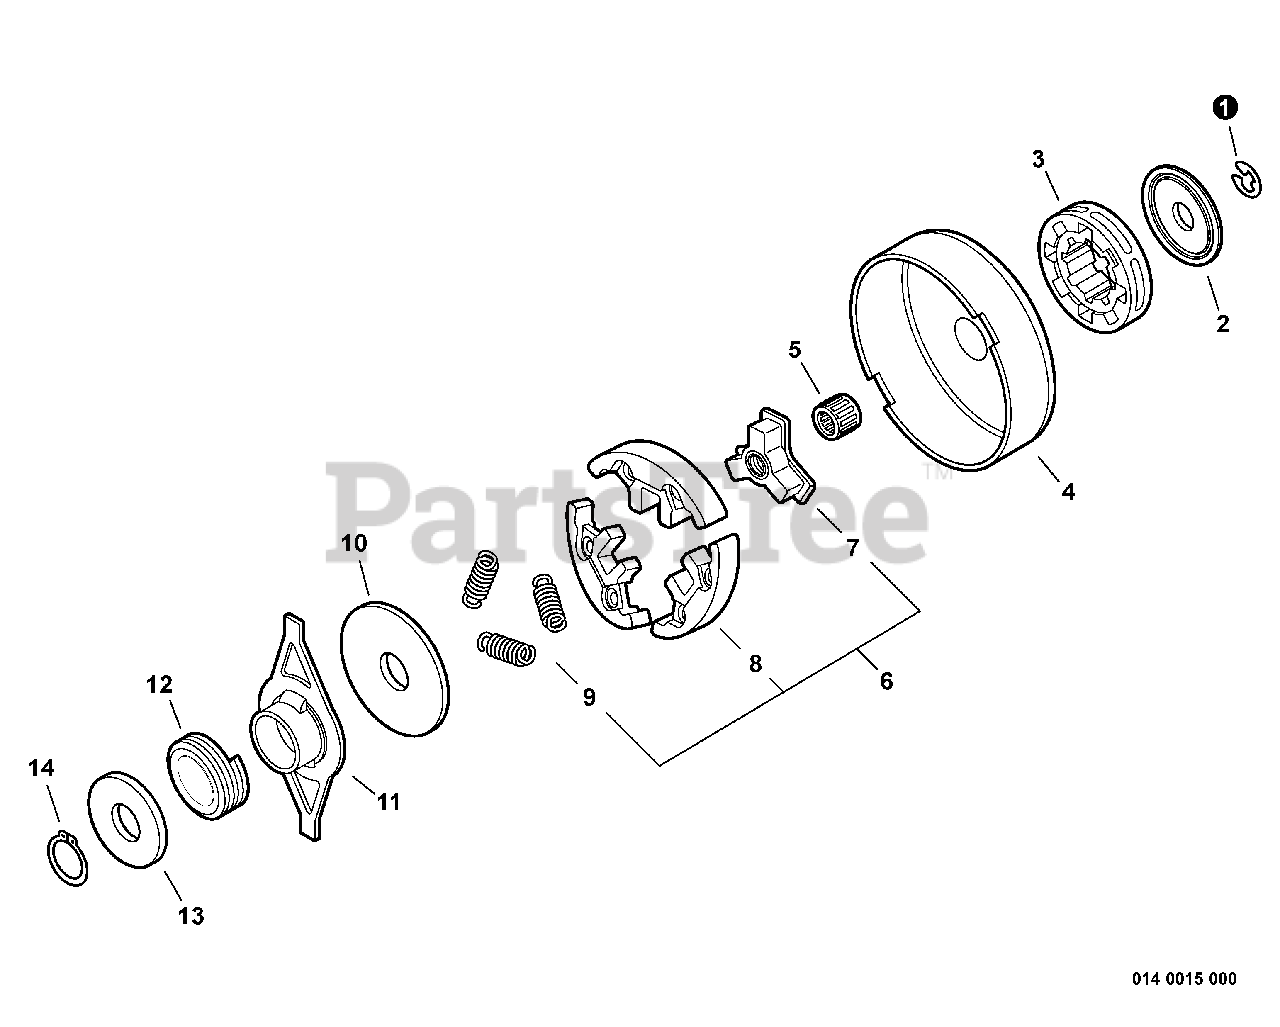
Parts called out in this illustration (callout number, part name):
1	RING, RETAINING - 8
2	WASHER - 10
3	SPROCKET, RIM
4	DRUM, CLUTCH
5	BEARING, NEEDLE
6	CLUTCH ASSY
7	HUB, CLUTCH
8	CLUTCH SHOE SET
9	SPRING, CLUTCH
10	PLATE, CLUTCH
11	RETAINER
12	GEAR - WORM
13	WASHER - 15
14	RING, RETAINING - 15
